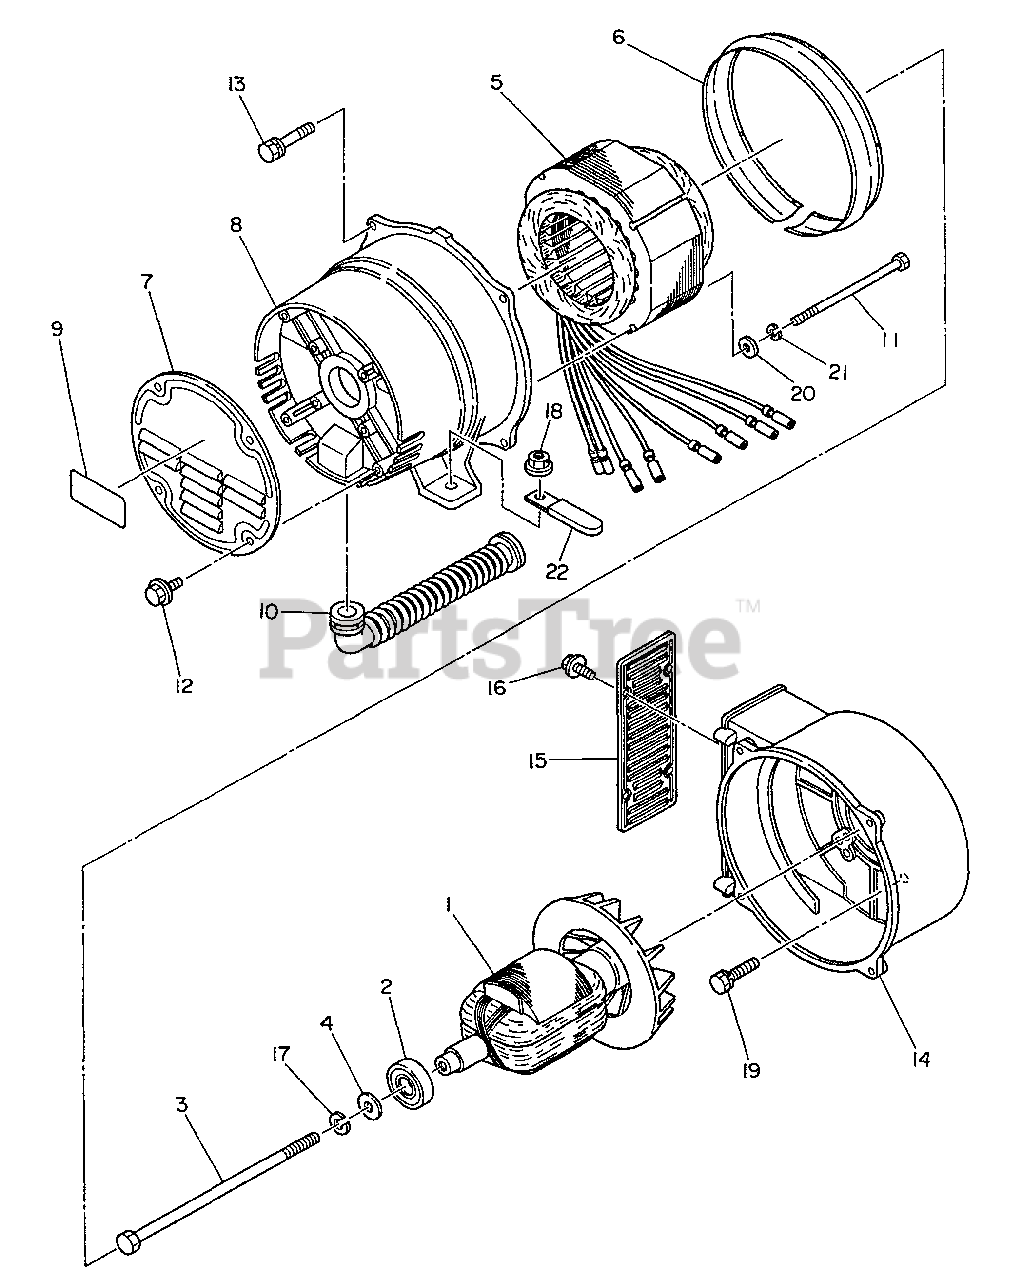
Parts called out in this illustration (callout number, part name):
1	ROTOR ASSY
2	BEARING, BALL - 6205RS
3	BOLT
4	WASHER
5	STATOR ASSY
6	SUPPORT RING
7	COVER
8	COVER - REAR
9	LABEL - DANGER
10	BUSHING
11	BOLT
12	BOLT - FLANGE
13	BOLT
14	COVER - FRONT
15	PROTECTOR
16	SCREW -- TAPPING
17	LOCKWASHER
18	NUT - 8 -- FLANGE
19	BOLT
20	WASHER
21	LOCKWASHER
22	CLAMP
